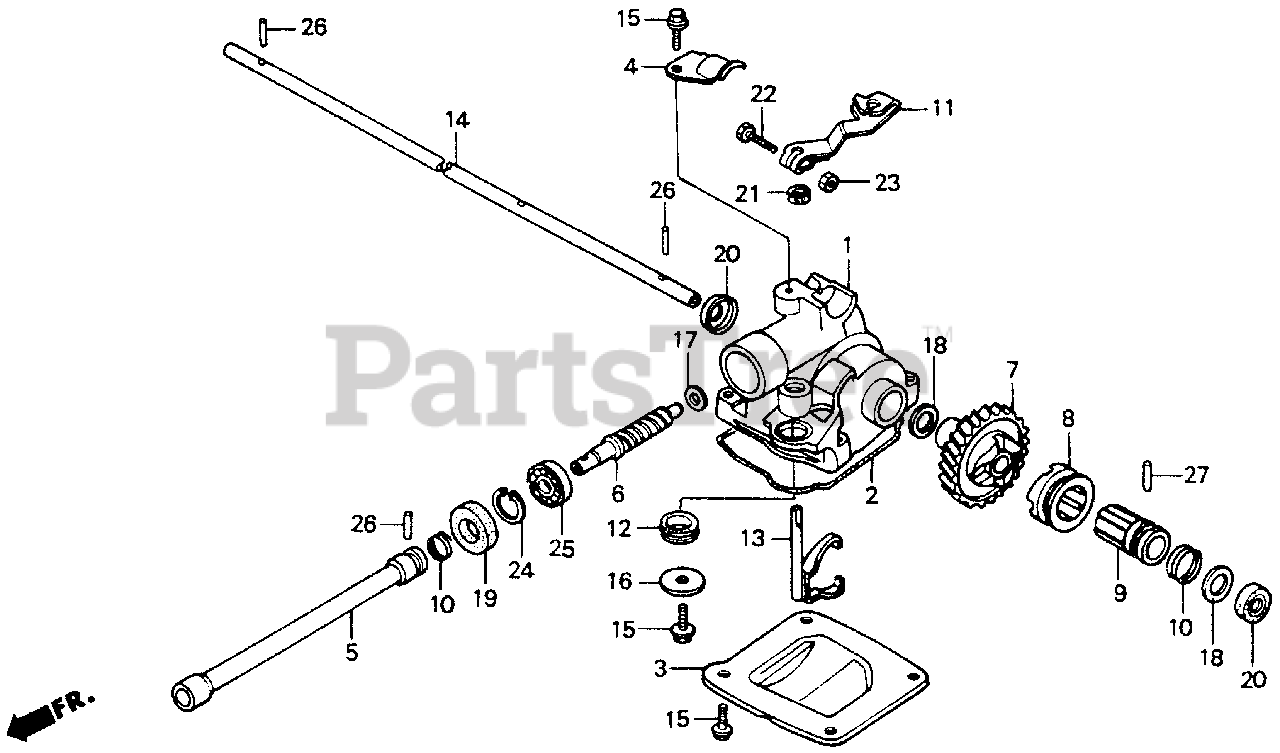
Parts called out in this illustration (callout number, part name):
1	CASE, GEAR (UPPER) (NOT AVAILABLE)
2	O-RING, CASE
3	COVER, GEAR CASE
4	HOLDER, WIRE
5	SHAFT, EXTENSION (NOT AVAILABLE)
6	GEAR, DRIVE (NOT AVAILABLE)
7	GEAR, DRIVEN
8	CLUTCH, DRIVEN
9	SHAFT, CLUTCH (NOT AVAILABLE)
10	CLIP, CLUTCH SHAFT
11	ARM, CLUTCH
12	MOUNT, RUBBER
13	SHAFT, SHIFT
14	SHAFT, DRIVE (NOT AVAILABLE)
15	BOLT, FLANGE (6X12) (CT200)
16	WASHER, PLAIN (22X6X1.6)
17	WASHER, THRUST (10.5X16.5X1)
18	WASHER, THRUST (12MM)
19	OIL SEAL (12X28X6)
20	OIL SEAL (12X22X5)
21	OIL SEAL (8X14X5)
22	BOLT, HEX. (6X20)
23	NUT, HEX. (6MM)
24	CIRCLIP, INNER (28MM)
25	BEARING, RADIAL BALL (6001)
26	ROLLER (4X17.8)
27	ROLLER (5X17.8)
